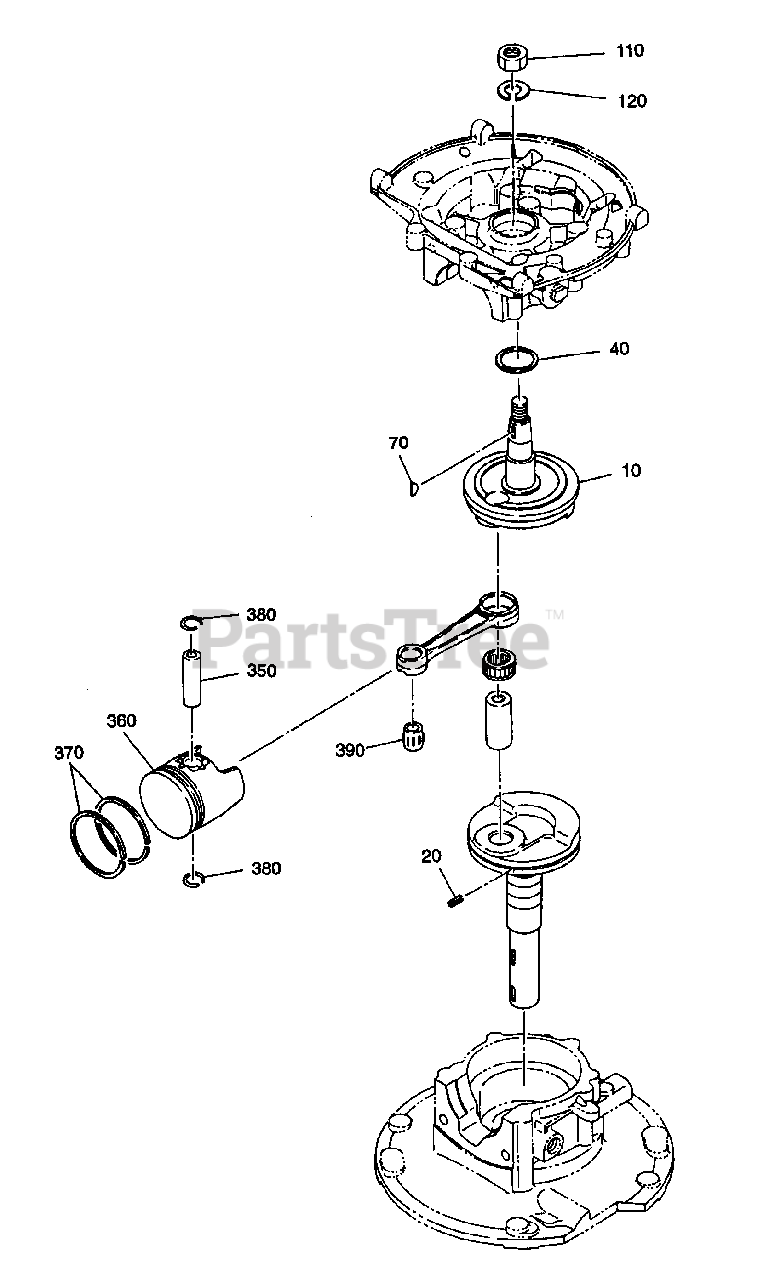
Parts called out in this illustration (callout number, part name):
10	CRANK SHAFT ASSY
40	SPACER
70	WOODRUFF KEY
120	SPRING WASHER
360	PISTON CP
360	PISTON CP 0.25
360	PISTON CP 0.50
370	PISTON RING SET STD
370	PISTON RING SET 0.25
370	PISTON RING SET 0.50
390	NEEDLE BEARING
